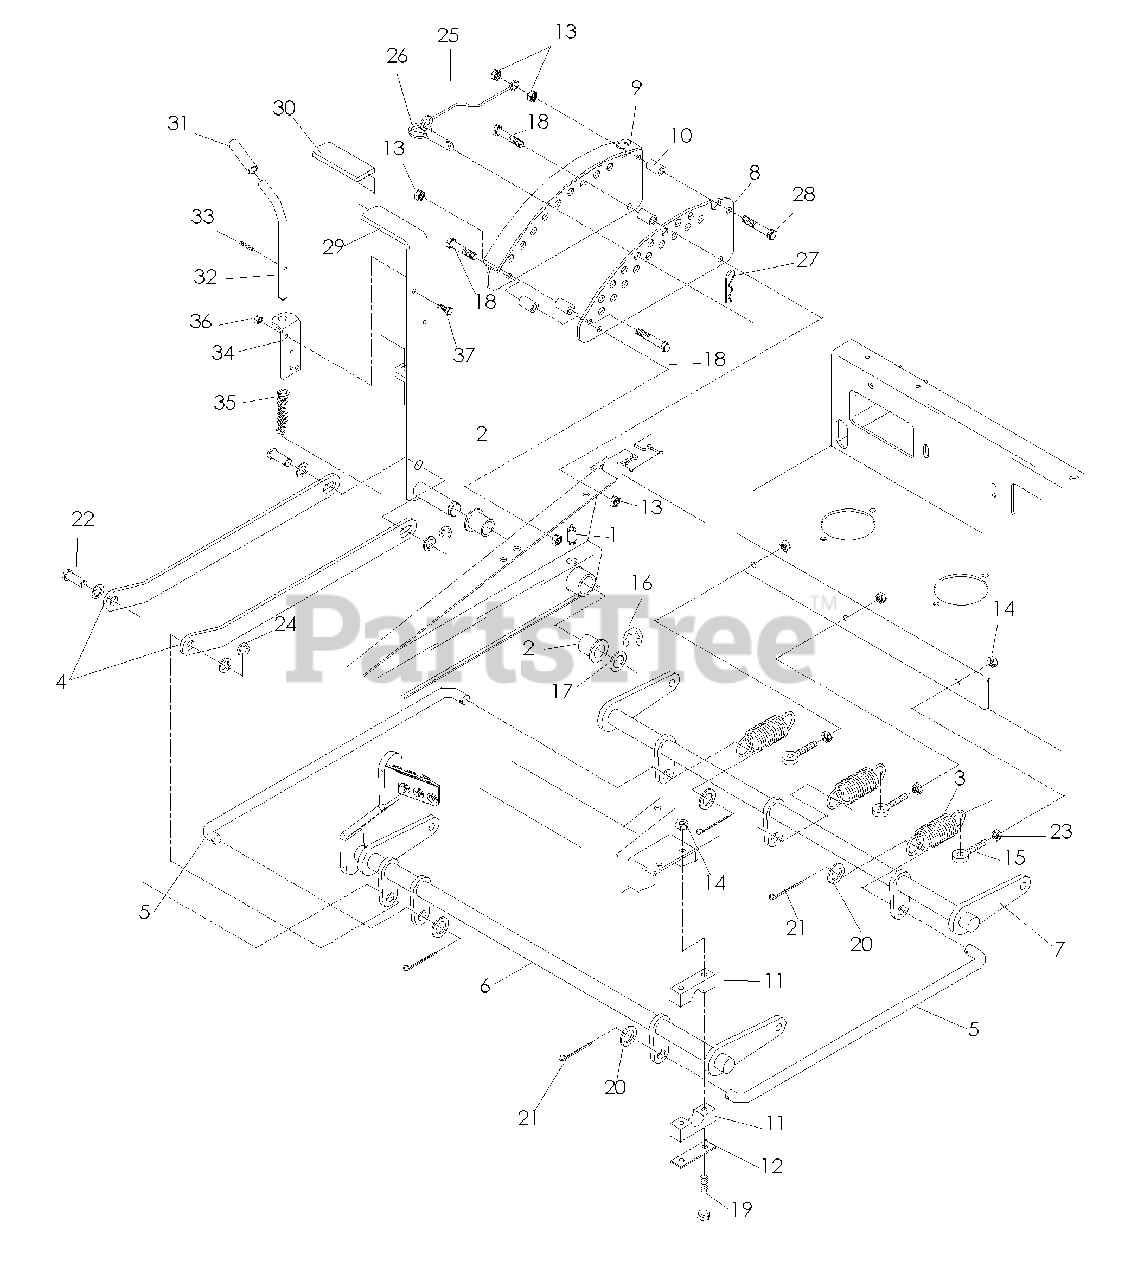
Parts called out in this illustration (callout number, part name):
1	ZERK, LONG
2	BUSHING, FLANGE
3	SPRING, DECK LIFT
4	LINKAGE, LIFT
5	LINK, CONNECTING
6	SHAFT ASSM W/PEDAL, FT
7	SHAFT, REAR LIFT
8	PLATE, ADJUSTMENT
9	PLATE, ADJUSTMENT
10	SPACER, DECK LIFT
11	BLOCKS, PILLOW
12	PLATE, SUPPORT
13	NUT 3/8-16 HEX NYLOC
14	NUT 5/16-18 HEX NYLOC
15	EYEBOLT 5/16 RH x 1 9/16
16	E-RING 7/8
17	BUSHING, MACHINE
18	HCS 3/8-16 x 2 1/2
19	HCS 5/16-18 x 2 3/4
20	WASHER 5/8 SAE
21	PIN, COTTER 5/32 x 1 1/4
22	PIN, CLEVIS 5/8
23	NUT 5/16-18 WHIZ
24	E-RING 5/8
26	PIN, HITCH
28	HCS 3/8-16 x 2 3/4
29	LEVER, LIFT
30	CUSHION, HANDLE
31	GRIP, VINYL
32	PIN, LOCKING
33	PIN, GROOVED
34	PIN MOUNT, UPPER
35	SPRING, COMPRESSION
36	NUT 1/4-20 CENTERLOCK
37	HCS 1/4- 20 x 3/4
